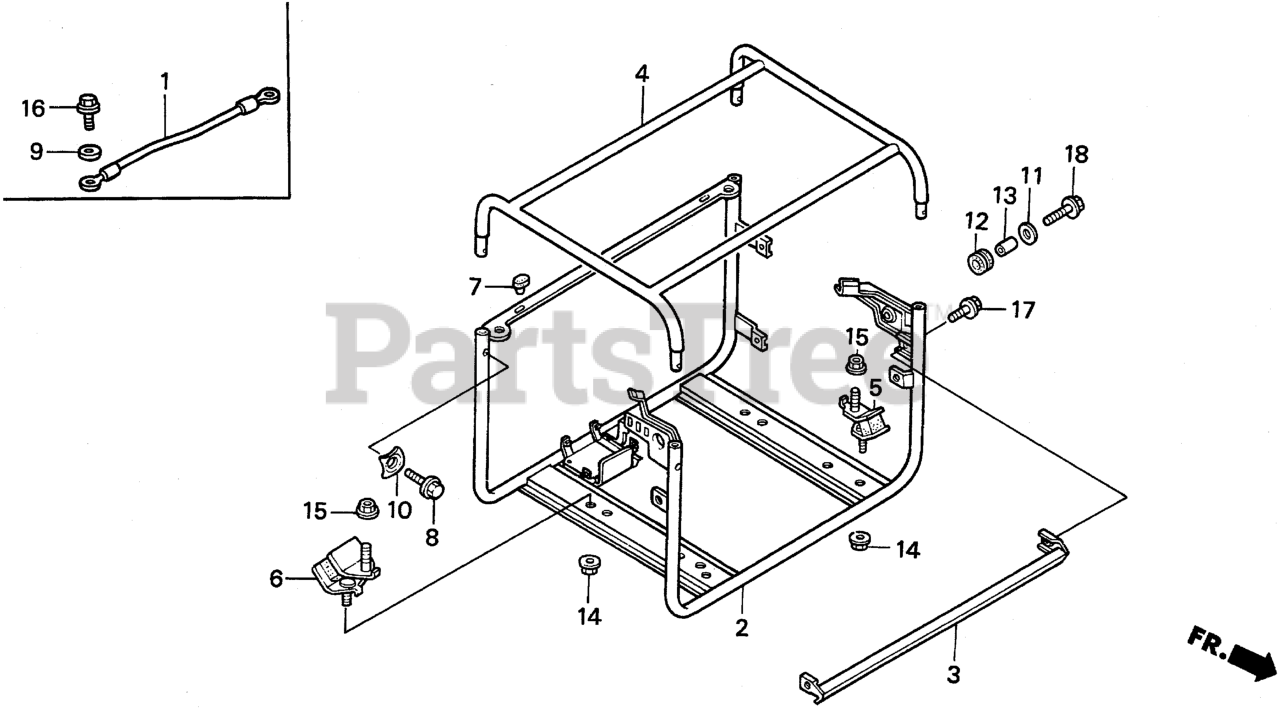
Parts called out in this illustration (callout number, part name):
1	CABLE, GROUND
2	FRAME (LOWER) *NH105* (MAT BLACK)
3	CHANNEL, FR. *NH105* (MAT BLACK)
4	FRAME (UPPER) *NH105* (MAT BLACK)
5	RUBBER (LOWER)
6	RUBBER (LOWER)
7	STOPPER, DISCHARGE GUARD Use up to Frame SN 1186736.
8	BOLT, FLANGE (8X20) (NOT AVAILABLE)
8	BOLT, FLANGE (8X16) Use from Engine SN 1000016.
8	BOLT, FLANGE (8X20) Use up to Engine SN 1609606.
9	WASHER, LOCK (6MM)
10	WASHER, FRAME JOINT
11	WASHER, AIR DUCT
12	RUBBER, CONTROL BOX
13	COLLAR, CONTROL BOX
14	NUT, FLANGE (8MM)
15	NUT, FLANGE (10MM)
16	BOLT, FLANGE (6X10)
17	BOLT, FLANGE (6X12) Use up to Engine SN 1543277.
18	BOLT, FLANGE (6X18)
